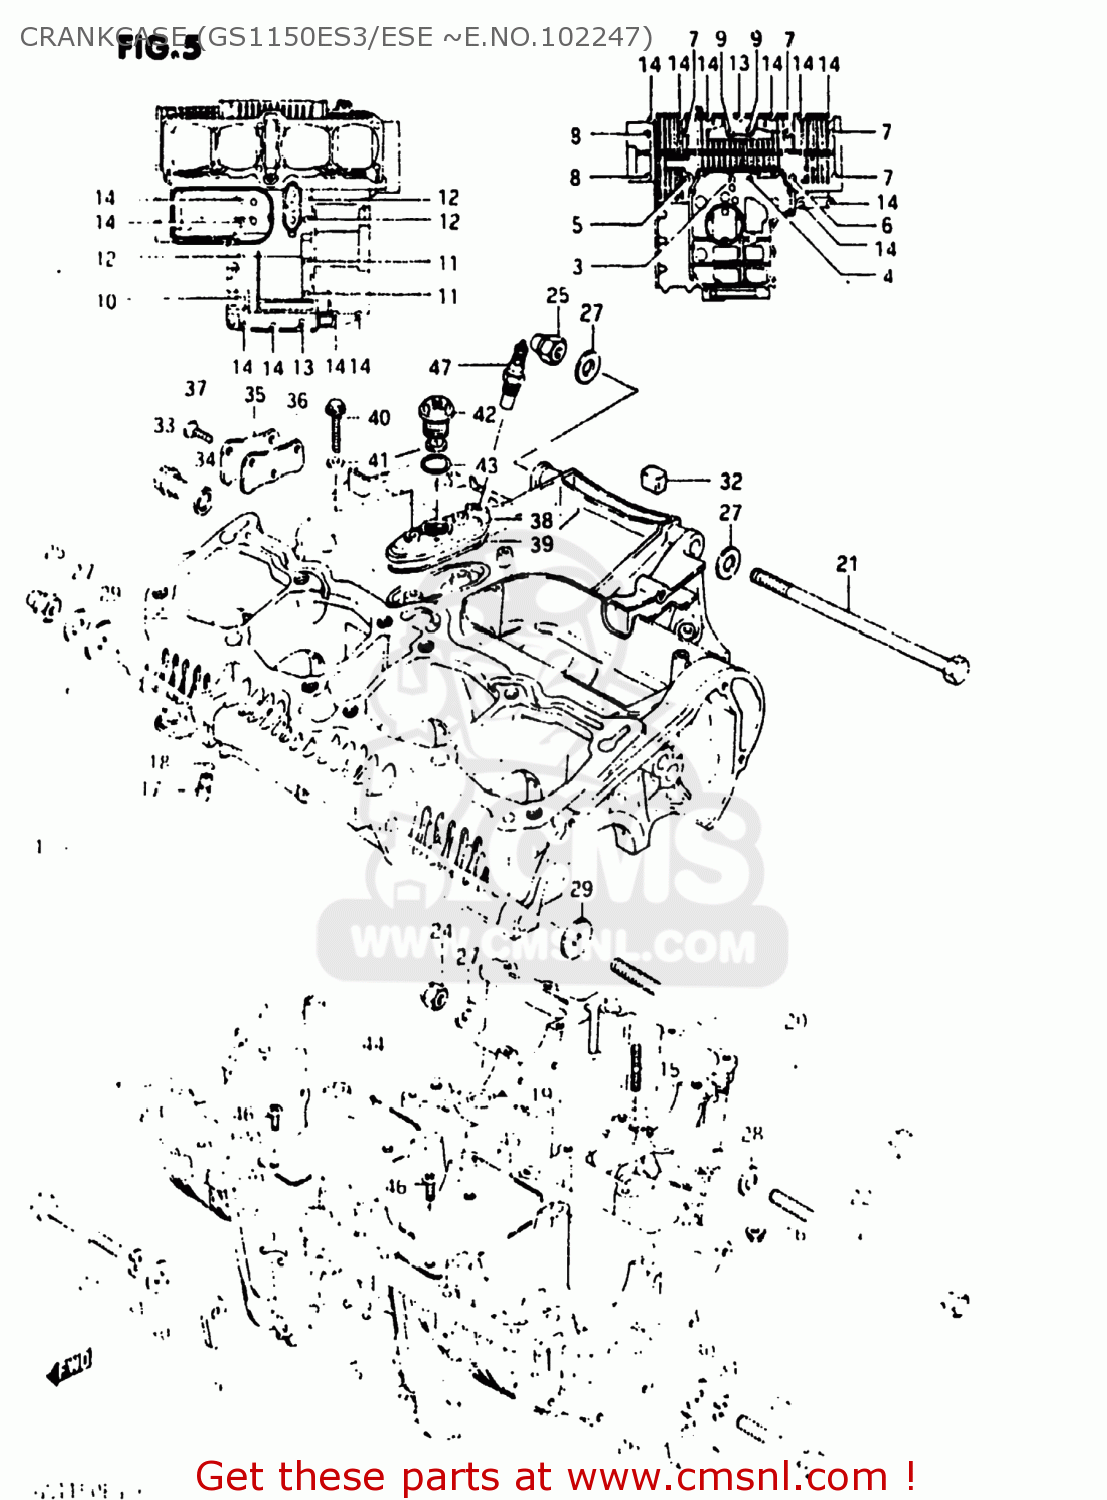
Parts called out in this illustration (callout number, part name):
1	CRANKCASE SET
2	PIN
3	BOLT
4	BOLT(8X135)
5	BOLT(8X115)
6	BOLT(8X100)
7	BOLT (8X90)
8	BOLT (8X65)
9	BOLT 8X60
10	BOLT, UPPER
11	BOLT
12	BOLT (6X75)
13	BOLT 6X55
14	BOLT
15	STUD 6X50
16	NUT
17	UNION
18	O RING(D:1.05,ID:3.1)
19	O RING(D:3.2,ID:12.9)
20	BOLT
21	BOLT 10X180
22	BOLT(10X165)
23	BOLT 10X60
24	NUT (10MM)
25	NUT
26	NUT
27	WASHER
28	WASHER
29	WASHER
30	WASHER (10.5X20X3.2)
31	LOCK WASHER
32	PAD,CYLINDER
33	PLUG (14X12)
34	GASKET(14X19.2X2) (NAS)
35	CAP,OIL GALLERY
36	GASKET,OIL GALLERY (MCA)
37	SCREW
38	HOUSING,OIL PRESSURE SWITCH
39	O RING,PRESSURE SWITCH HOUSING
40	BOLT
41	WASHER
42	SWITCH ASSEMBLY
43	O RING(D:1.9,ID:18.8)
44	PLATE,OIL SEPARATOR
45	PLATE,OIL SEPARATOR
46	SCREW
47	GAUGE ASSEMBLY,OIL TEMPERATURE
